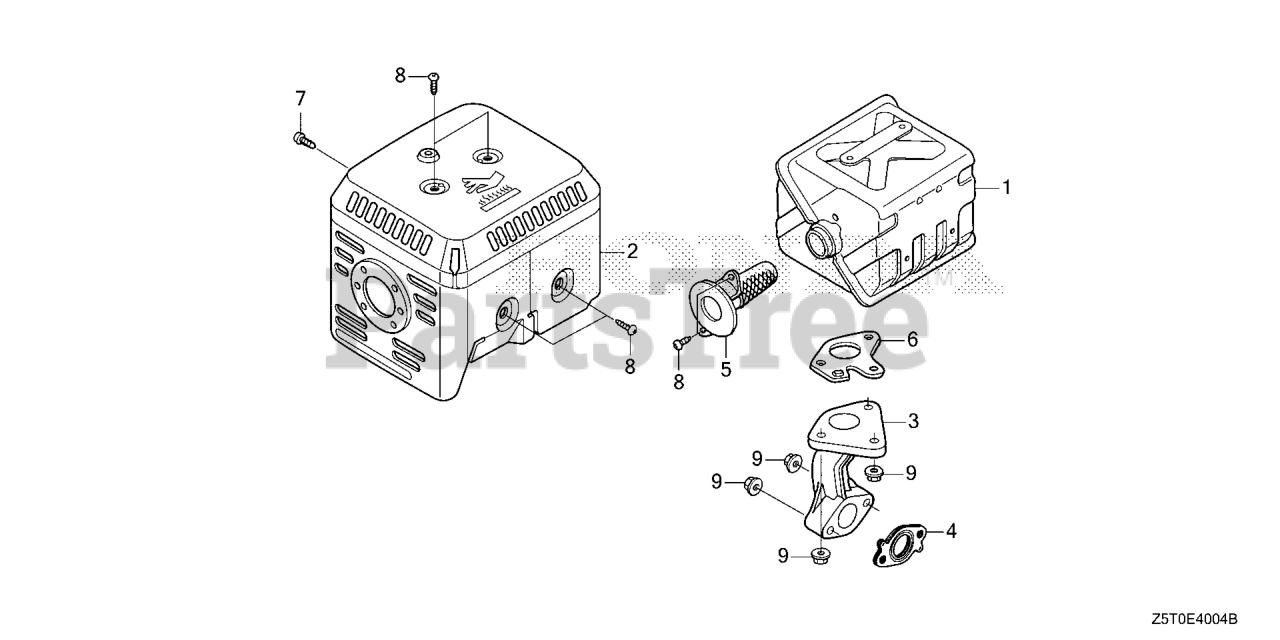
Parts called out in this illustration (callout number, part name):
1	MUFFLER
2	PROTECTOR, MUFFLER
5	ARRESTER, SPARK
6	GASKET, MUFFLER (ARRESTER)
6	GASKET, MUFFLER (ARRESTER)(THAI LEAKLESS)
7	SCREW, TAPPING (6X10)
8	SCREW, TAPPING (5X8)
9	NUT, FLANGE (8MM)
